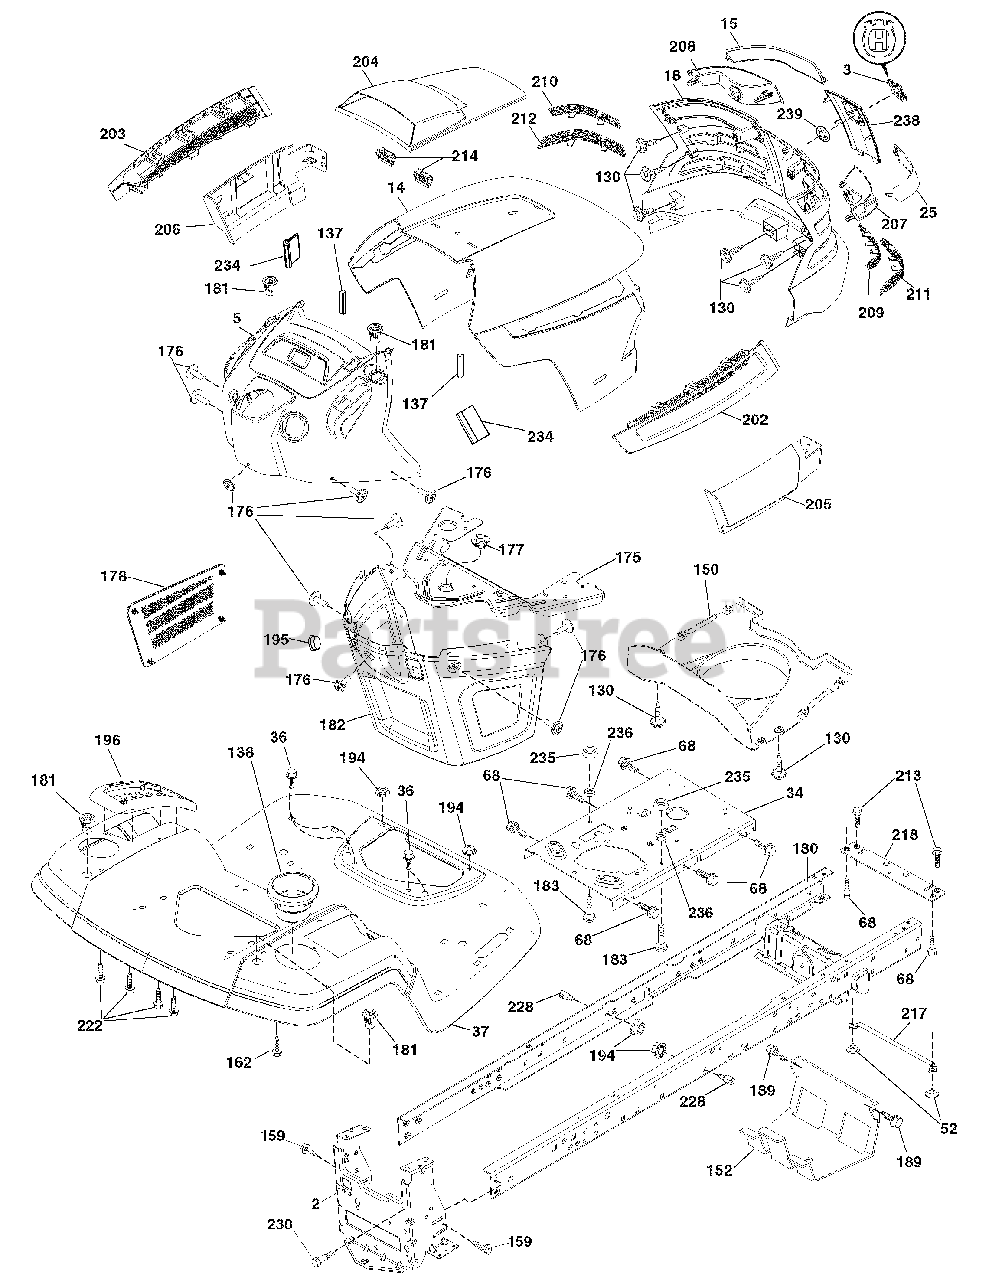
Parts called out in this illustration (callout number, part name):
3	Logo
4	Logo
14	Hood
18	Grille/Lens Asm.
34	Plate Engine
36	Screw 5/16-18 x 3/4
37	Fender
52	Nut Lock 5/16-18
68	Screw Thdrol 5/16-18 x 1/2
130	Screw 10 x 3/4 Single Lead-Hex
137	Bumper Dash
138	Cupholder
152	Shield Browning
159	Screw Hexwsh Thdr 3/8-16 x 3/4
175	Crossmember
176	Screw 10-24 x 5/8
177	Bushing Steering
178	Cargo Net Asm.
180	Chassis
181	Bushing Mtg. Fender Crgo
182	Dash Lower
183	Bolt Fin Hex 5/16-18 unc x 1-1/4
189	Screw 5/16-18 x 3/4
194	Nut Lock Hex Flange 5/16-18
195	Plug Hole Dash Lower
196	Console Asm. Deck Lift
202	Vent Side Hood RH
203	Vent Side Hood LH
204	Vent Top Hood
205	Skirt Hood Side RH
206	Skirt Hood Side LH
209	Insert Hex Top RH
210	Insert Hex Top Lh
211	Insert Hex Bottom RH
212	Insert Hex Bottom LH
213	Bolt 5/16-18 x 3/4
214	Clip Retainer Tinner
218	X-Piece Hood Stop
222	Screw Thdrol 1/4-20 x 5/8
228	Stud Fastner
230	Bolt Shoulder 5/16-18
234	Bumper Hood
235	Spacer Fender
236	Nut Lock 5/16-18 UNC
